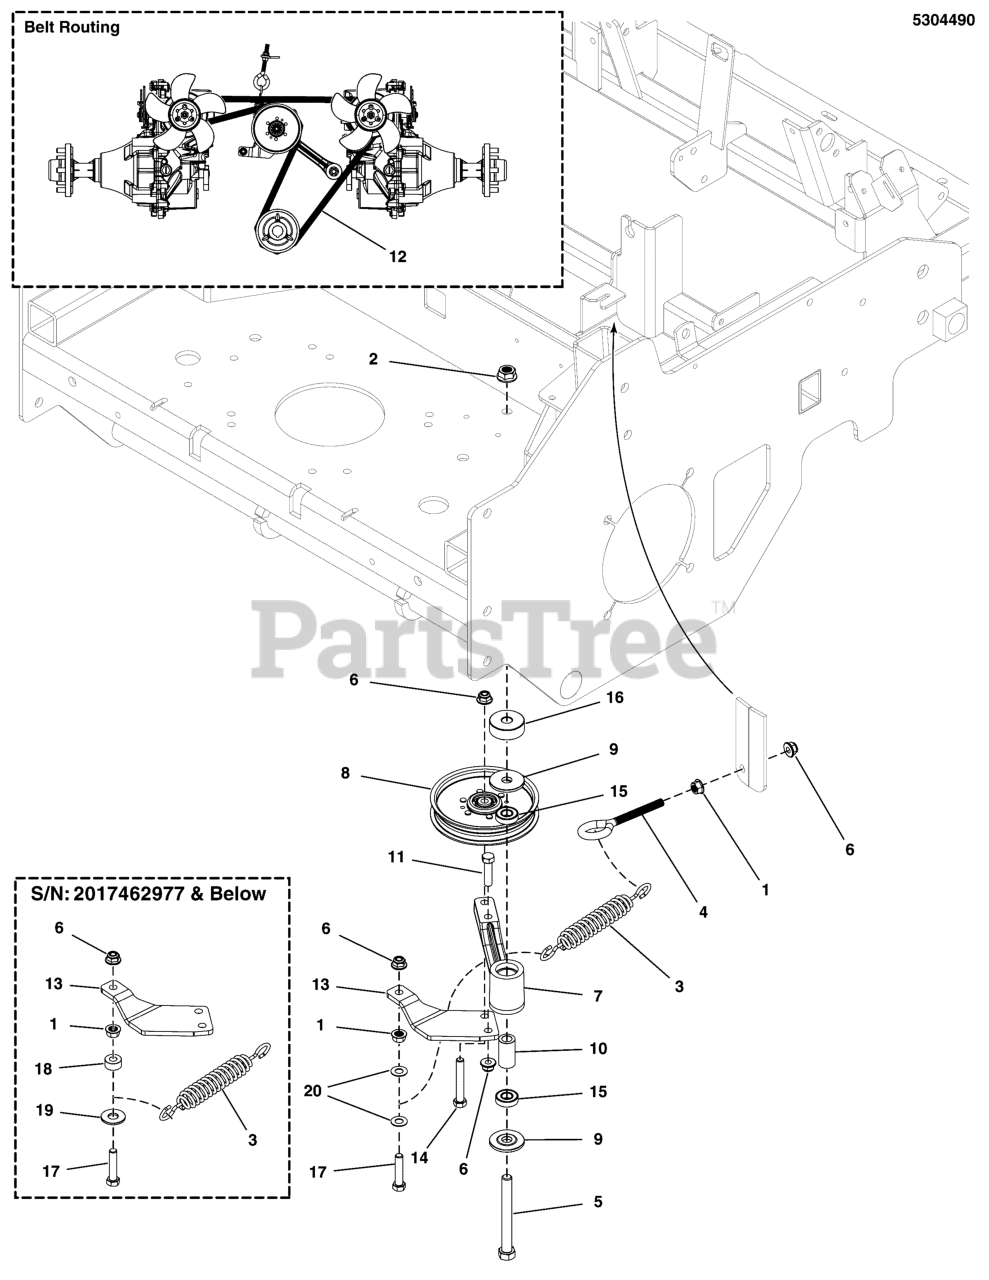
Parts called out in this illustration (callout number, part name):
1	NUT, 3/8-16 HEX SERRATED FLANGE
2	NUT, Hex Flange, Nylock, 1/2-13
3	SPRING-EXT, 1.04 ODX6.935LGX.148WR, BLK
4	EYE BOLT, 3/8-16 X 5, 2.88THRD, 1EYE, CZ
5	BOLT, 1/2-13 X 4-1/2 GD5 CZ
6	NUT, 3/8-16 HEX NYLOCK FLANGE
7	ASSM, IDLER ARM, PUMP DRIVE, 1/2ID, CAST (SV)
8	PULLEY-IDLER, 5.00OD, .385ID, .75W, STL
9	SPACER, IDLER ARM, 1/2, PM
10	SPACER, .52 X .84 X 1.53, PM
11	BOLT, 3/8-16 X 1-1/2" GD5 CZ
12	BELT, HB SEC, 81.2EL
13	PLATE, IDLER ARM ADAPTER - BLK
14	BOLT, 3/8-16 X 2-1/2" GD5 CZ
15	BEARING, BALL, AXLE
16	SPACER, .52 X 1.75 X .63, CZ
17	BOLT, 3/8-16 X 1-3/4" GD5 CZ
18	SPACER, .39 X 1.00 X .25, PM, CZ
19	WASHER-3/8 FENDER
20	WASHER, 3/8 USS
